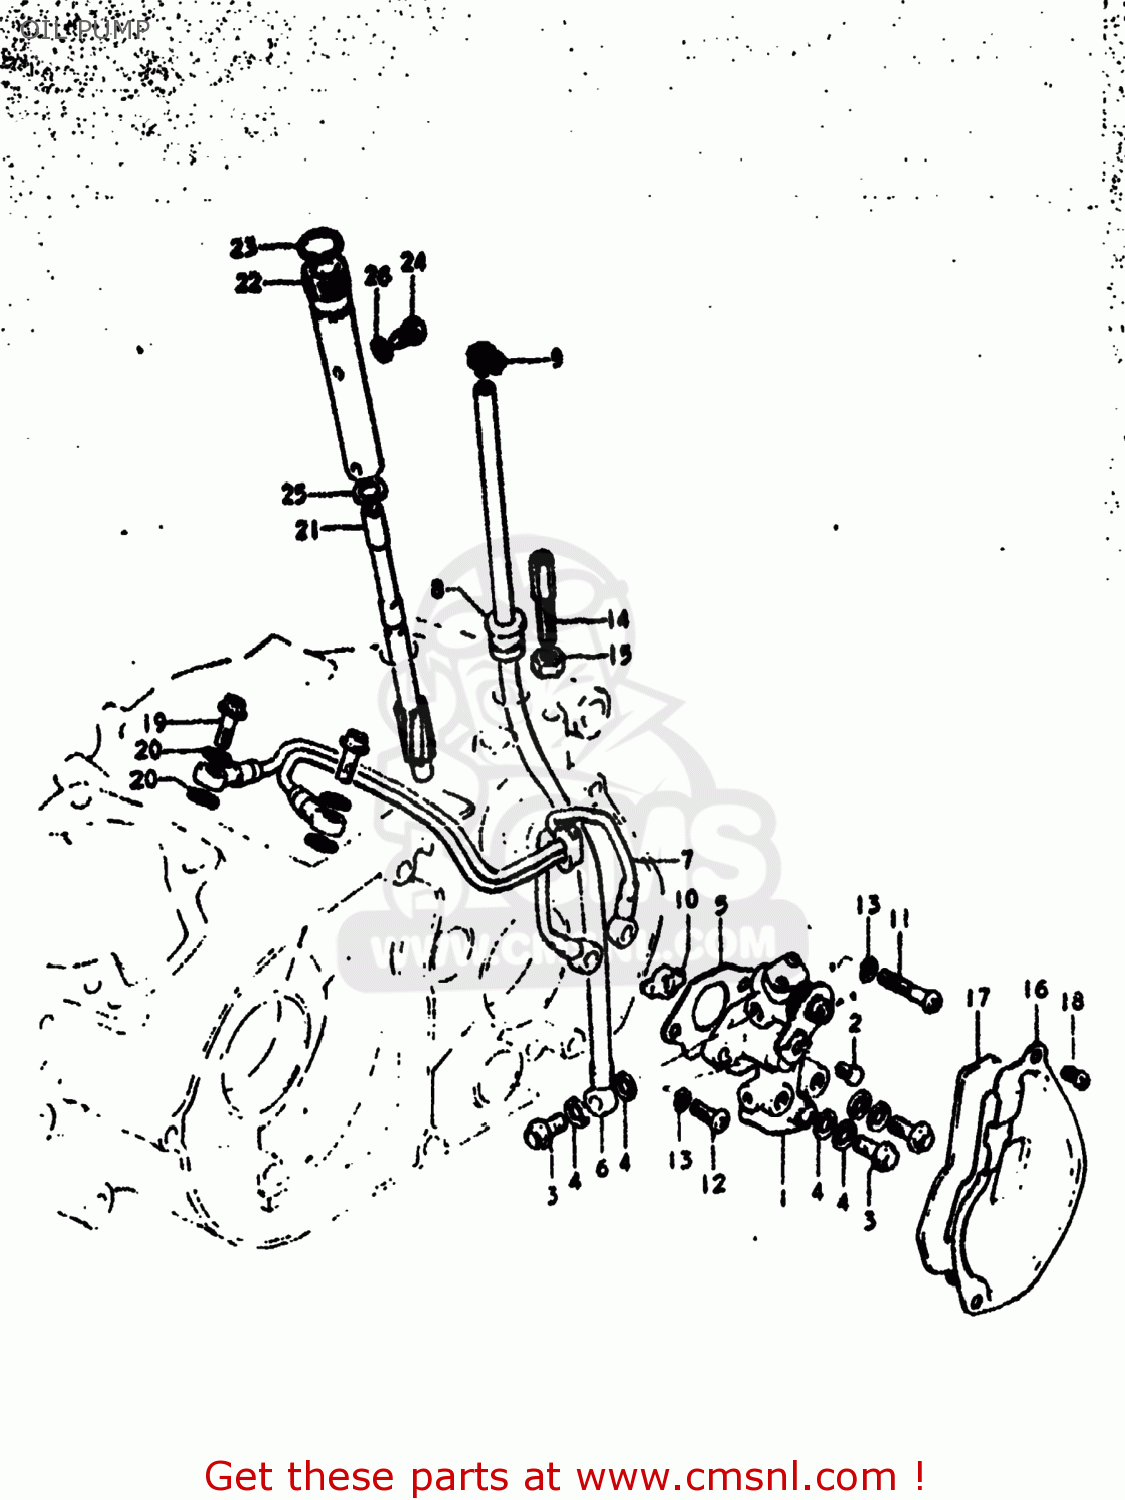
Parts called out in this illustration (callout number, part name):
1	PUMP ASSEMBLY,OIL
2	TERMINAL,CABLE
3	UNION BOLT
4	GASKET (NAS)
5	GASKET,OIL PUMP (MCA)
6	HOSE,OIL NO.1
7	HOSE,OIL NO.2
8	BUSHING
9	CLAMP
10	PIECE,OIL PUMP DRIVE
11	SCREW
12	SCREW
13	LOCK WASHER
14	BOLT
15	NUT
16	CAP,OIL PUMP INSPECTION
17	GASKET,OIL PUMP INSPECTION (NAS)
18	SCREW
19	UNION BOLT
20	GASKET(6.2X11X1).2 (NAS)
21	GEAR,TACHOMETER DRIVEN
22	SLEEVE,TACHOMETER DRIVE
23	O RING(D:1.3,ID:9.6)
24	BOLT(6X12)
25	WASHER(8X13.7X1)
26	WASHER
